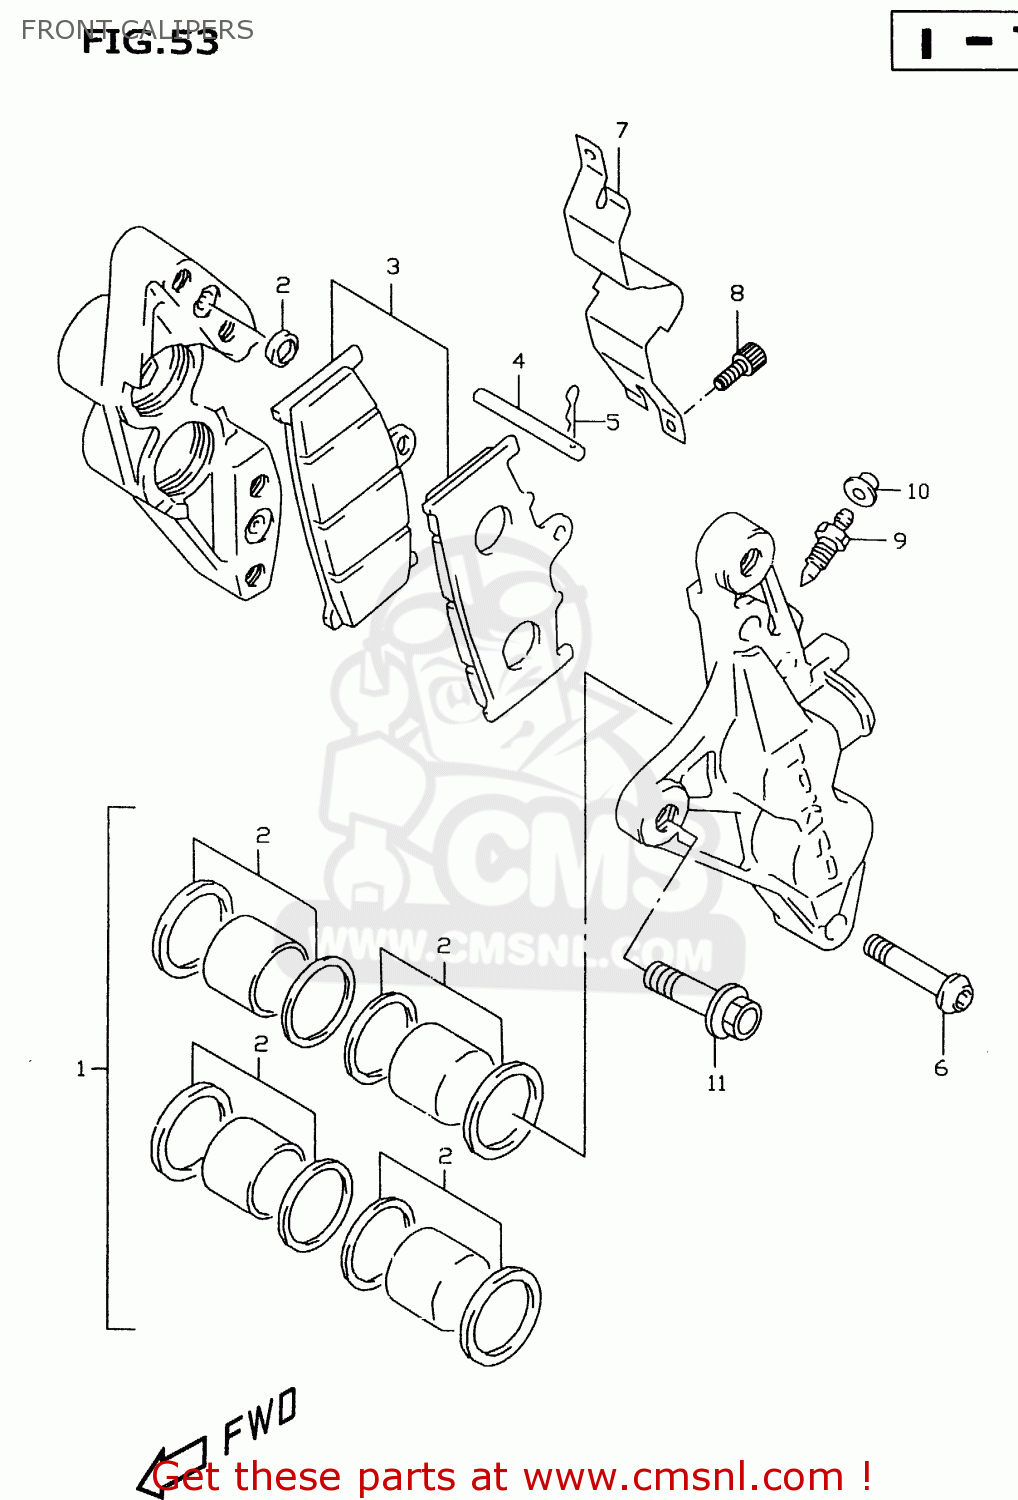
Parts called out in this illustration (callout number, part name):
1	PISTON SET
2	SEAL SET,PISTON
3	PAD SET (NAS)
4	PIN,PAD
5	CLIP,PAD PIN
6	BOLT,HOUSING
7	COVER,CALIPER DUST,R
8	SCREW
9	BLEEDER
10	CAP,BLEEDER PLUG
11	BOLT(10X30)
